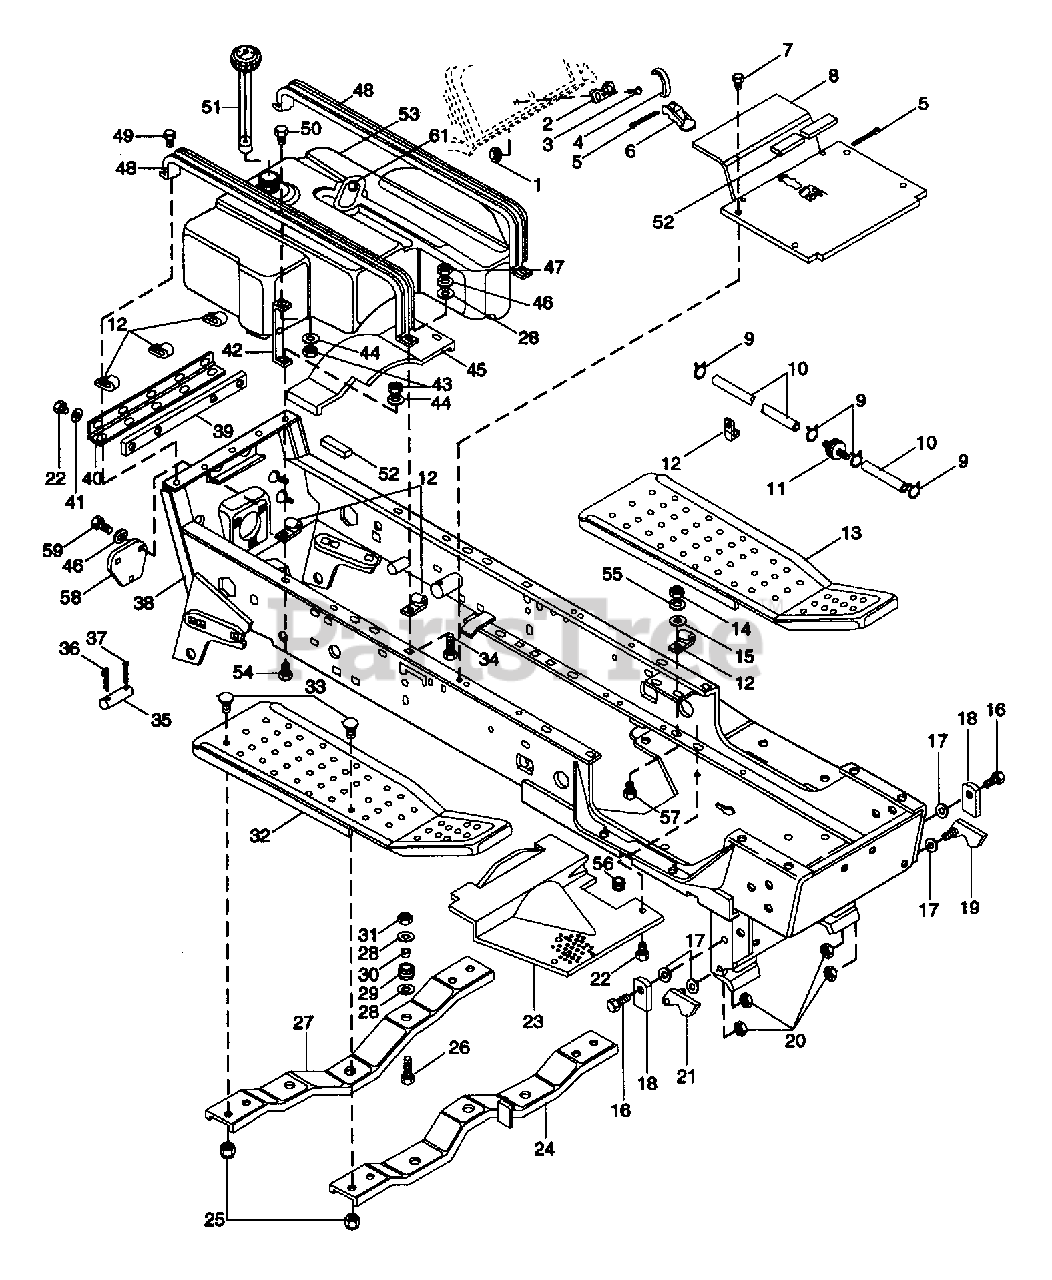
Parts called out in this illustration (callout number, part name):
1	NUT-LK DUAL FACE 10-24 PL
3	SCR-MCH 10-24X.50 SLRH PL
4	SPRING - DECK LATCH
5	PIN-COTR .12 X 1.25 PL
6	LEVER - DECK LATCH
7	SCR-TAP .250-20X.37 HWH PL TR
8	FLOOR PLATE
9	CLAMP-HOSE WIR.490/.510X.092#8
10	FUEL LINE 1/4 X 67"
11	FUEL FILTER
12	J-CLAMP
13	L.H. RUNNING BOARD
14	NUT-HEX .375-16
15	WSHR-FL-STL .438X1.0X.083 PL
16	BLT-HEX .38-16X1.00 PL
17	SPRING WASHER
18	LOCK STOP
19	LATCH LH
20	NUT-LK TOP .375-16 GR C YWZC
21	LATCH RH
22	SCR-TAP .312-18X.50 HWH PL TR
24	FRONT CHANNEL
25	NUT-FLG. .312-18 PL
26	BLT-HEX .31-18X1.25 PL GR2
27	REAR CHANNEL
28	WSHR-FL-STL .38X.875X.083 PL
29	GROMMET .438ID X .688 OD
30	SPACER .318X.430X.375
31	NUT-LK .312-18 GR A PL
32	R.H. RUNNING BOARD
33	BLT-RDHDSQSHNK .31-18X.50 YZ
34	BLT-RDHDSQNK .31-18X.75 SHT PL
36	PIN-HAIR INT .14X.4X2.75
37	PIN-COTR .12X1.0 PL
38	MAIN FRAME TWIN
40	HINGE-2" X 12.88 YWZC
41	WSHR-FL-STL.344X.688X.065PL
42	SUPPORT
43	NUT-HEX .250-20 PL
44	WSHR-LK .250X.077 HVY PL
46	WSHR-LK .312X.097 PL HVY
47	NUT-HEX .312-18
48	CHANNEL
49	SCR-TAP .312-18X.75 HWH PL TR
50	SCR .25-20X.75 TS PH PL
51	GAS GAUGE & CAP
52	FOAM TAPE
53	GAS TANK ASSEMBLY
54	BLT-RDHDSQNK .25-20X.75
55	WSHR-LK .375X.115 HVY PL
56	GROMMET 1.0ID X 1.38 OD
57	BLT-RDHDSQNK .38-16X1.0 PL
59	BLT-HEX .31-18X.75 PL GR2
60	BSHG-SLV .750X.814X .750 BRZ
61	FITTING - GAS TANK
